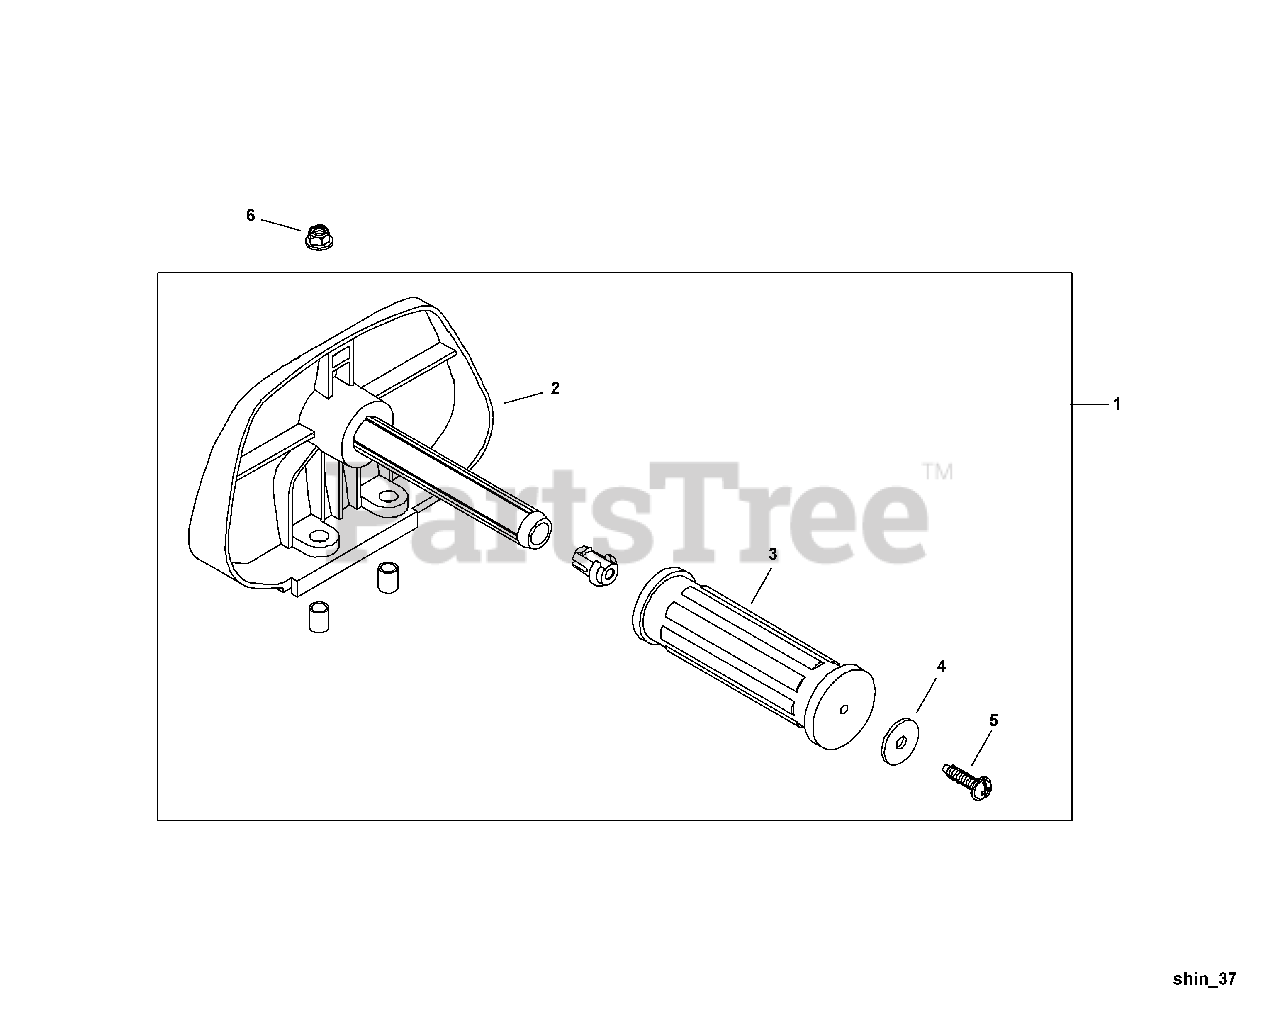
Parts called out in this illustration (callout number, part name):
1	HANDLE ASSY, FRONT
2	HANDLE, FRONT
4	WASHER 5 MM
5	SCREW 5×20
